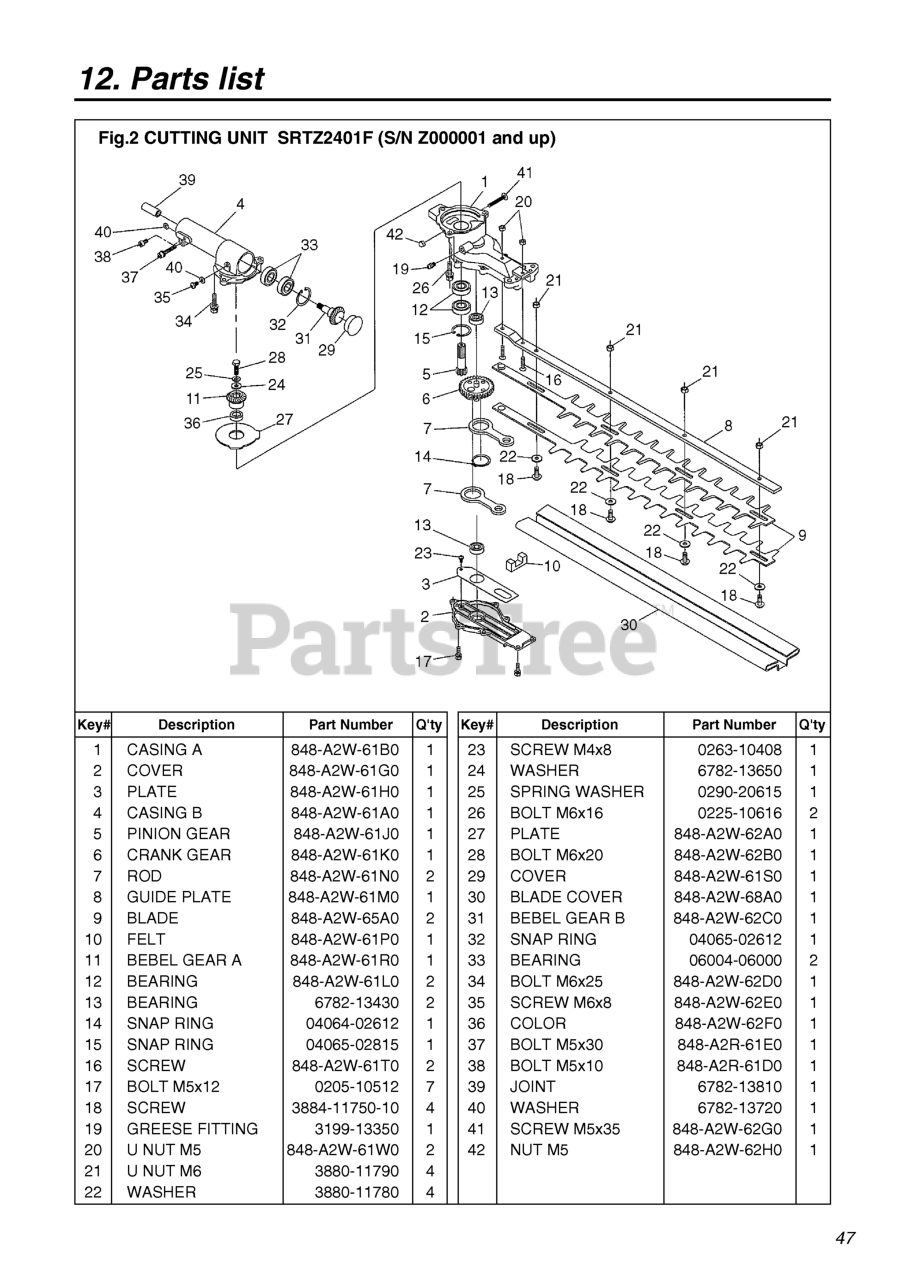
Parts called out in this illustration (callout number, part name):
1	CASING A
2	COVER
3	PLATE
4	CASING B
5	PINION GEAR
6	CRANK GEAR
7	ROD
8	GUIDE PLATE
9	BLADE
10	FELT
11	BEBEL GEAR A
12	BEARING
13	BEARING
14	SNAP RING
15	SNAP RING
16	SCREW
17	BOLT
18	SCREW (RPLS 3884-11750)
19	FITTING, GREASE
20	U NUT
21	NUT, M6
22	WASHER (RPLS 3873-11760)
23	SCREW, M4 X 8
24	WASHER, 6X15X2.0
25	WASHER, M6 X 15
26	BOLT, M6 x 16
27	PLATE
28	BOLT
29	COVER
30	BLADE COVER
31	BEBEL GEAR B
32	RING, SNAP, M26 X 1.2
33	BEARING
34	BOLT
35	SCREW
36	COLOR
37	BOLT
38	BOLT
39	JOINT (REPLACES T3078-13810)
40	WASHER
41	SCREW
42	NUT
